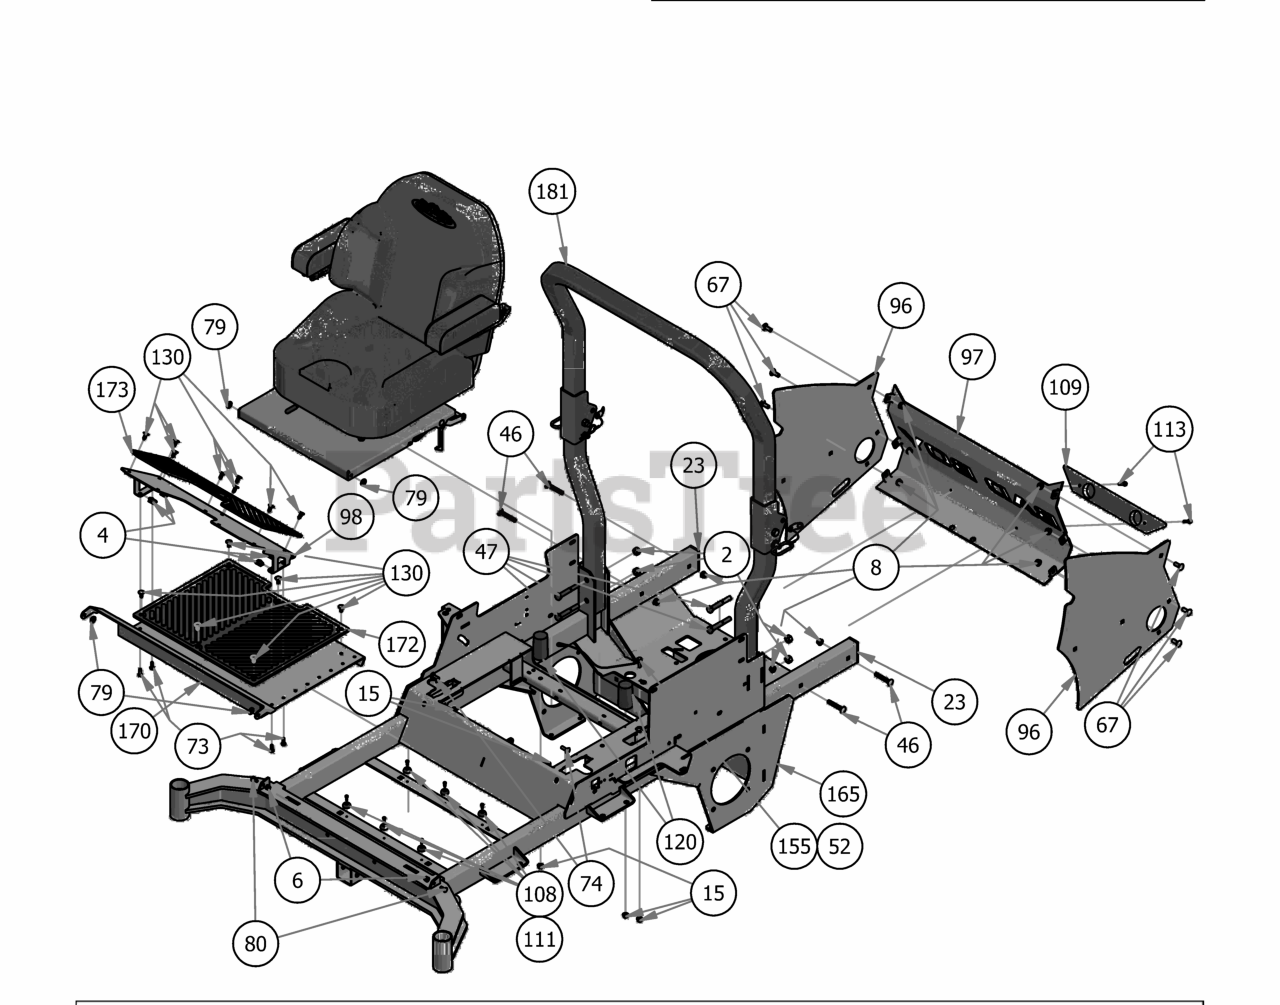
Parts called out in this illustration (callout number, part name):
2	1/2" Center Lock Nut
4	1/4-20 Cage Nut
6	1/4-20 Nylon Insert flange Nut
8	3/8" Nylock Flange Nut
15	5/16" Nylon Flange Nut
18	5/16" Flange Nut
20	5/16-18 Nylock Jam Nut 1/2 Nut
23	1 1/2 x 3 Frame Plug
43	M6-1.0 X 16MM Hex Bolt
46	3/8" x 2 1/2" Carriage Bolt
47	1/2-13 X 3.25 Hex Bolt - Grade 5
52	5/16" x 1" Bolt
63	5/16" x 1 1/4" Carriage Bolt
67	3/8" x 1" Carriage Bolt
73	1/4" x 3/4" Hex Bolt
74	5/16" x 1" Carriage Bolt
79	.360 ID Plastic Washer
80	1/4" x 3/4" Carriage Bolt
95	2019 Outlaw Seat Plate
96	2019 Rebel Rear Cover Side Plate
97	2019 Vertical Rear Cover Tailgate Plate
98	2019 Outlaw Adjustable Foot Plate
105	Seat Latch Rod Assembly
108	Button Bumper
109	2017 XP Bumper
111	#10 x 1/2" Self Tapping Screw
113	1/4 x 1 Hex Head Tek screw
120	2019 Bad Boy X Cylindrical Seat Mount
124	Brake Spring
130	Ratchet Fastener
155	Seat Cable
156	2019 Outlaw EPA Cannister Assembly
165	2019 Rigid Frame
166	2019 Rebel Seat
167	2019 Renegade Seat (Kawasaki FX1000 Only)
170	2019 Outlaw Floorboard
172	OUTLAW2019_FLOORMAT
173	FLOORMAT_OUTLAW_2019
181	2019 2X2 Folding ROPS
